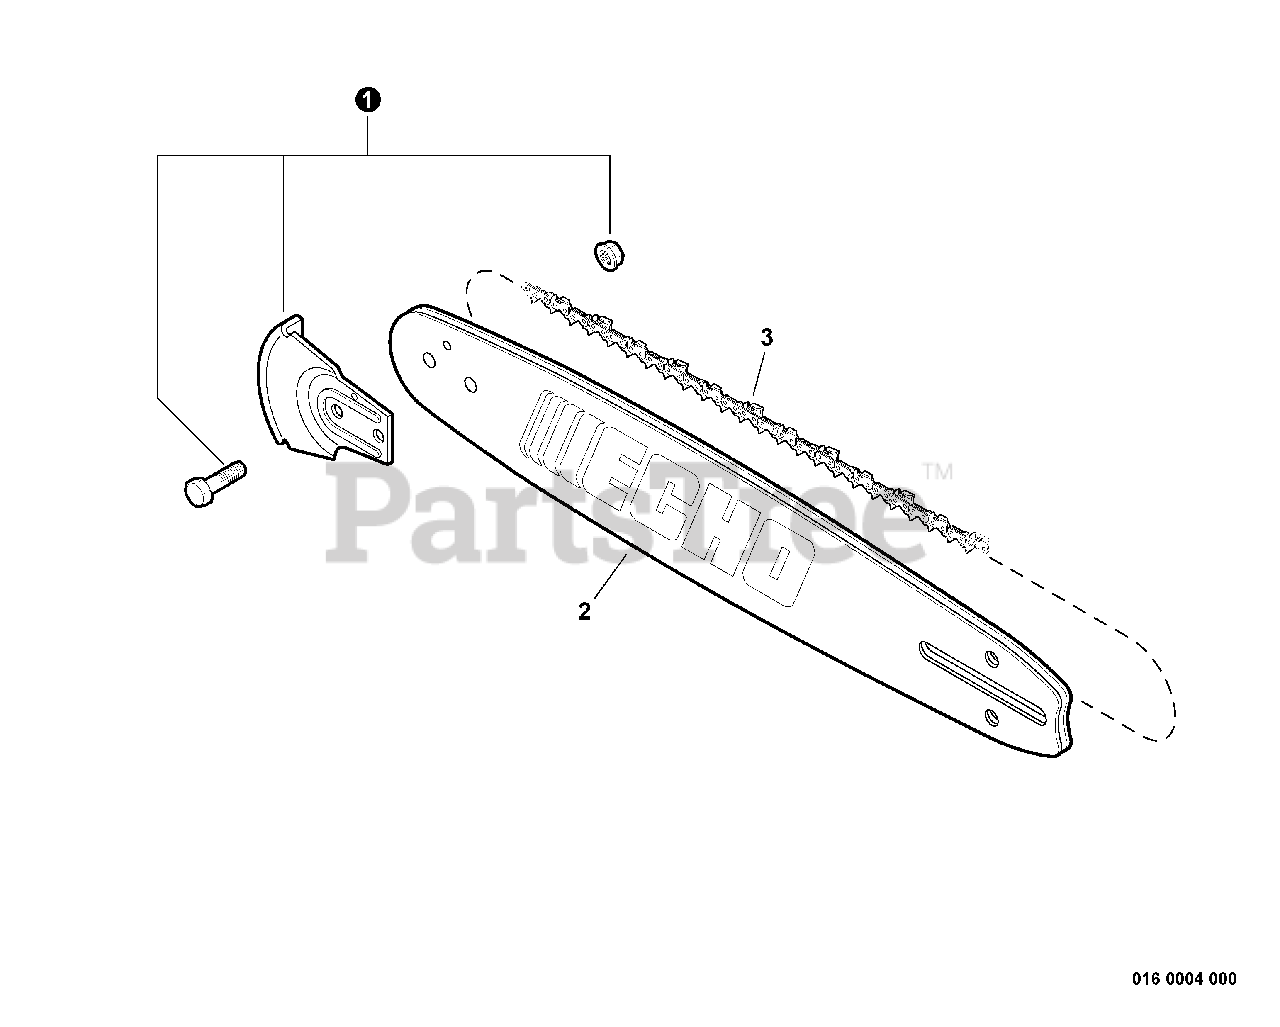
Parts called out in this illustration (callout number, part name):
1	KICK GUARD KIT
2	GUIDE BAR, 14" PRO 91
3	SAW CHAIN 14" XTRAGUARD
